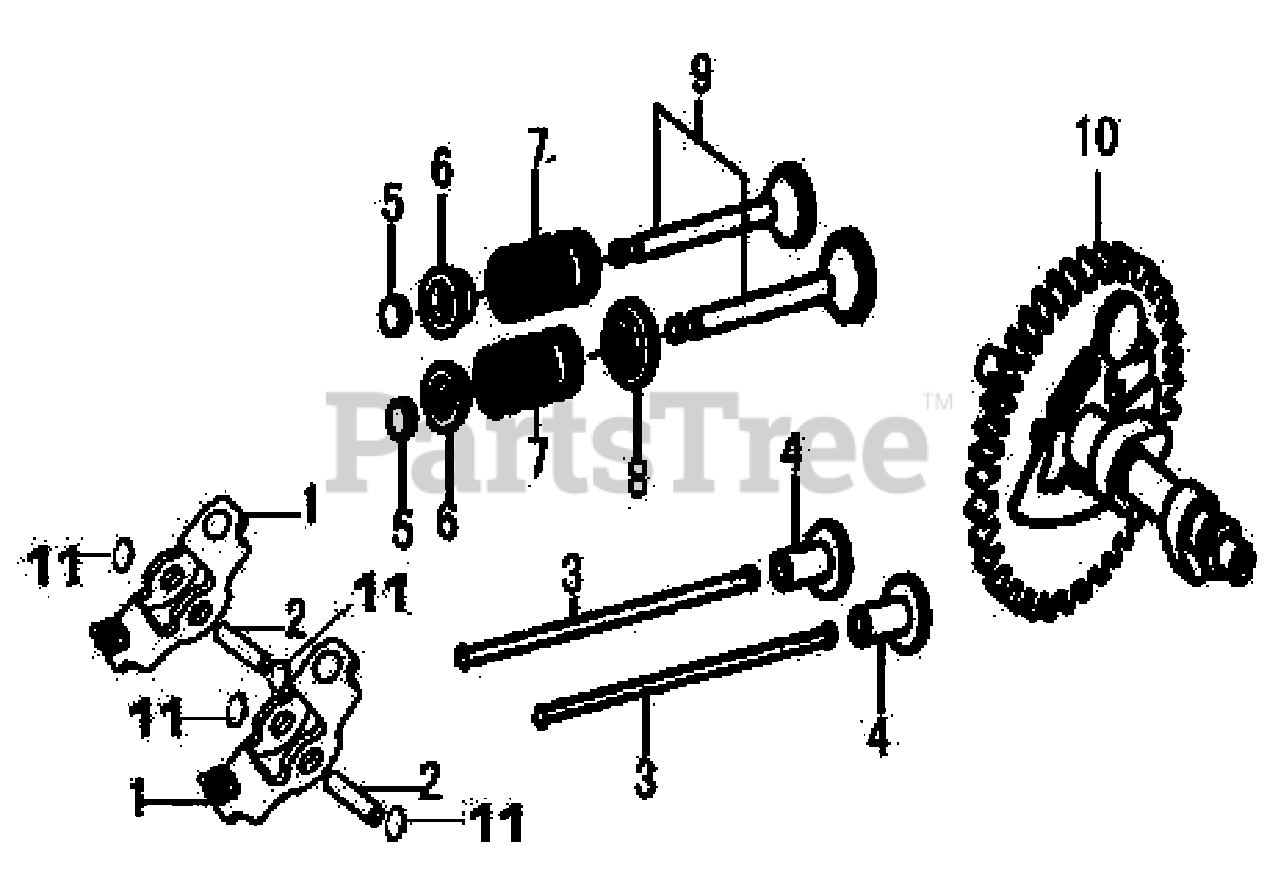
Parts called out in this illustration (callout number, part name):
1	ARM, ROCKER
2	VALVE ROCKER SHAFT
3	ROD, PUSH
4	LIFTER VALVE
5	ROTATOR, VALVE
6	RETAINER, VALVE SPRING
7	SPRING, VALVE
8	SEAL, GUIDE
9	VALVE SET
10	CAMSHAFT ASSEMBLY
11	WASHER, SPLIT
